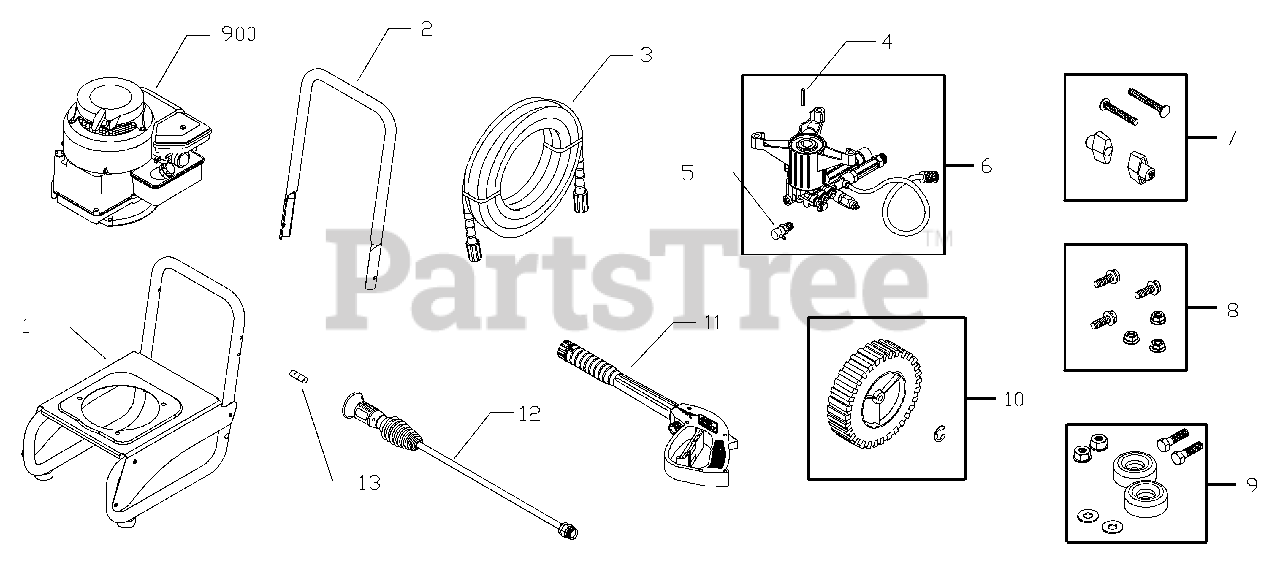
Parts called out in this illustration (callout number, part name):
3	HOSE
5	THERMAL RELIEF
6	ASSY, Pump
7	KIT, Fastening Handle
8	KIT, Pump/Engine Mounting Hardware
9	KIT, Vibration Mount
11	GUN
12	WAND
900	ENGINE
